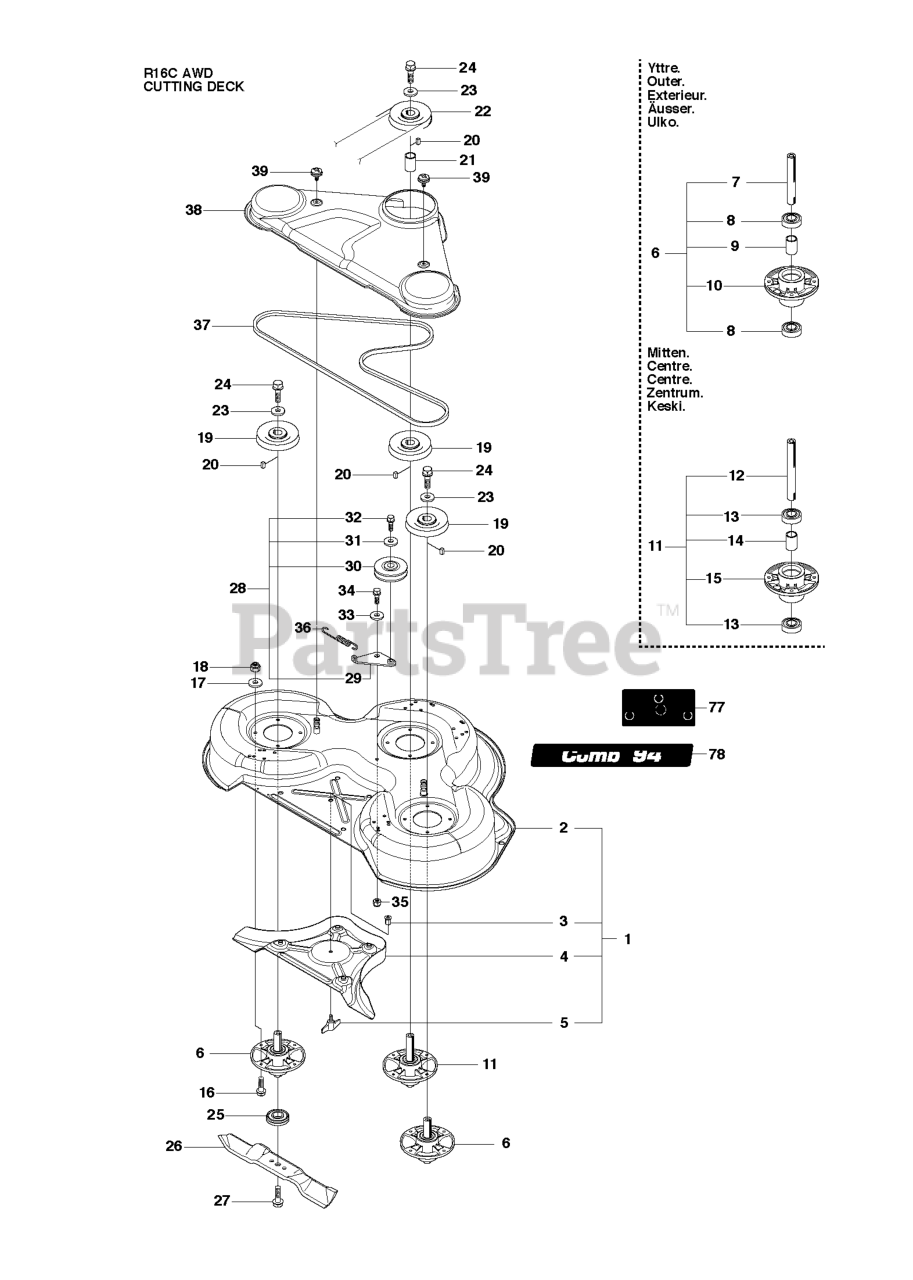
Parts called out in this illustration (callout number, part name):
4	PLUG C93 & C94
6	RP SPINDLE ASSY
10	BEARING HOUSING
15	BEARING HOUSING
17	WASHER BRB 8.4X17
18	LOCKNUT M8
21	SPACING SLEEVE
25	BLADE BRACKET
30	PULLEY
33	WASHER
35	LOCKNUT M8
